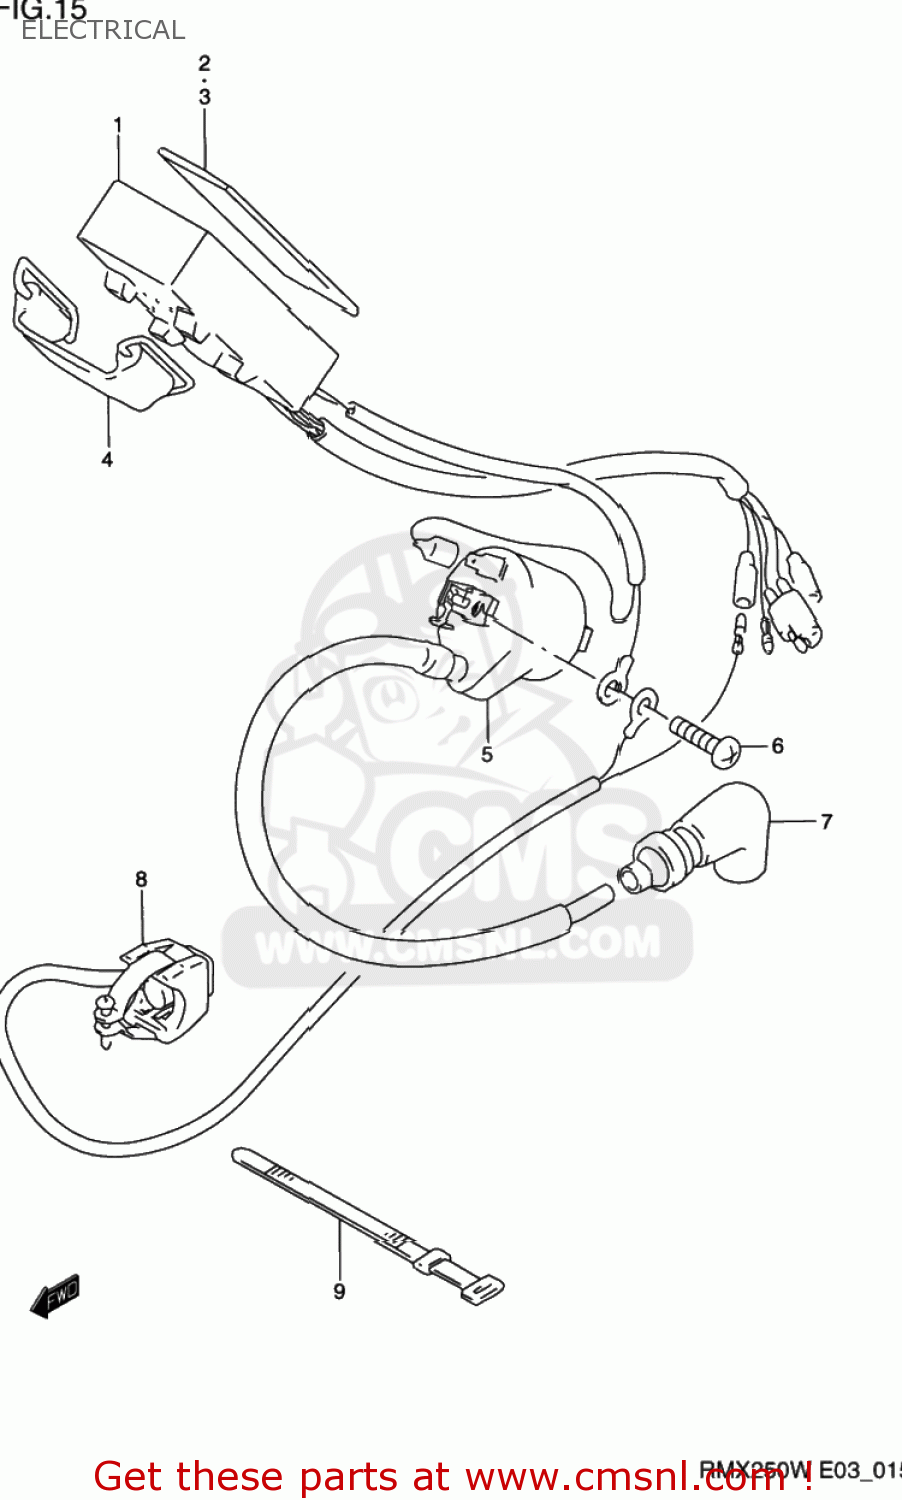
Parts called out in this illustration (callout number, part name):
1	CDI UNIT
2	PROTECTOR(170X95X3.0)
3	PROTECTOR(170X95X3.0)
4	BAND(L:65)
5	COIL ASSY,IGNITION NO.1
6	SCREW, 6X20
7	CAP,SPARK PLUG
8	SWITCH ASSY,ENGINE STOP
9	CLAMP(L:120)
